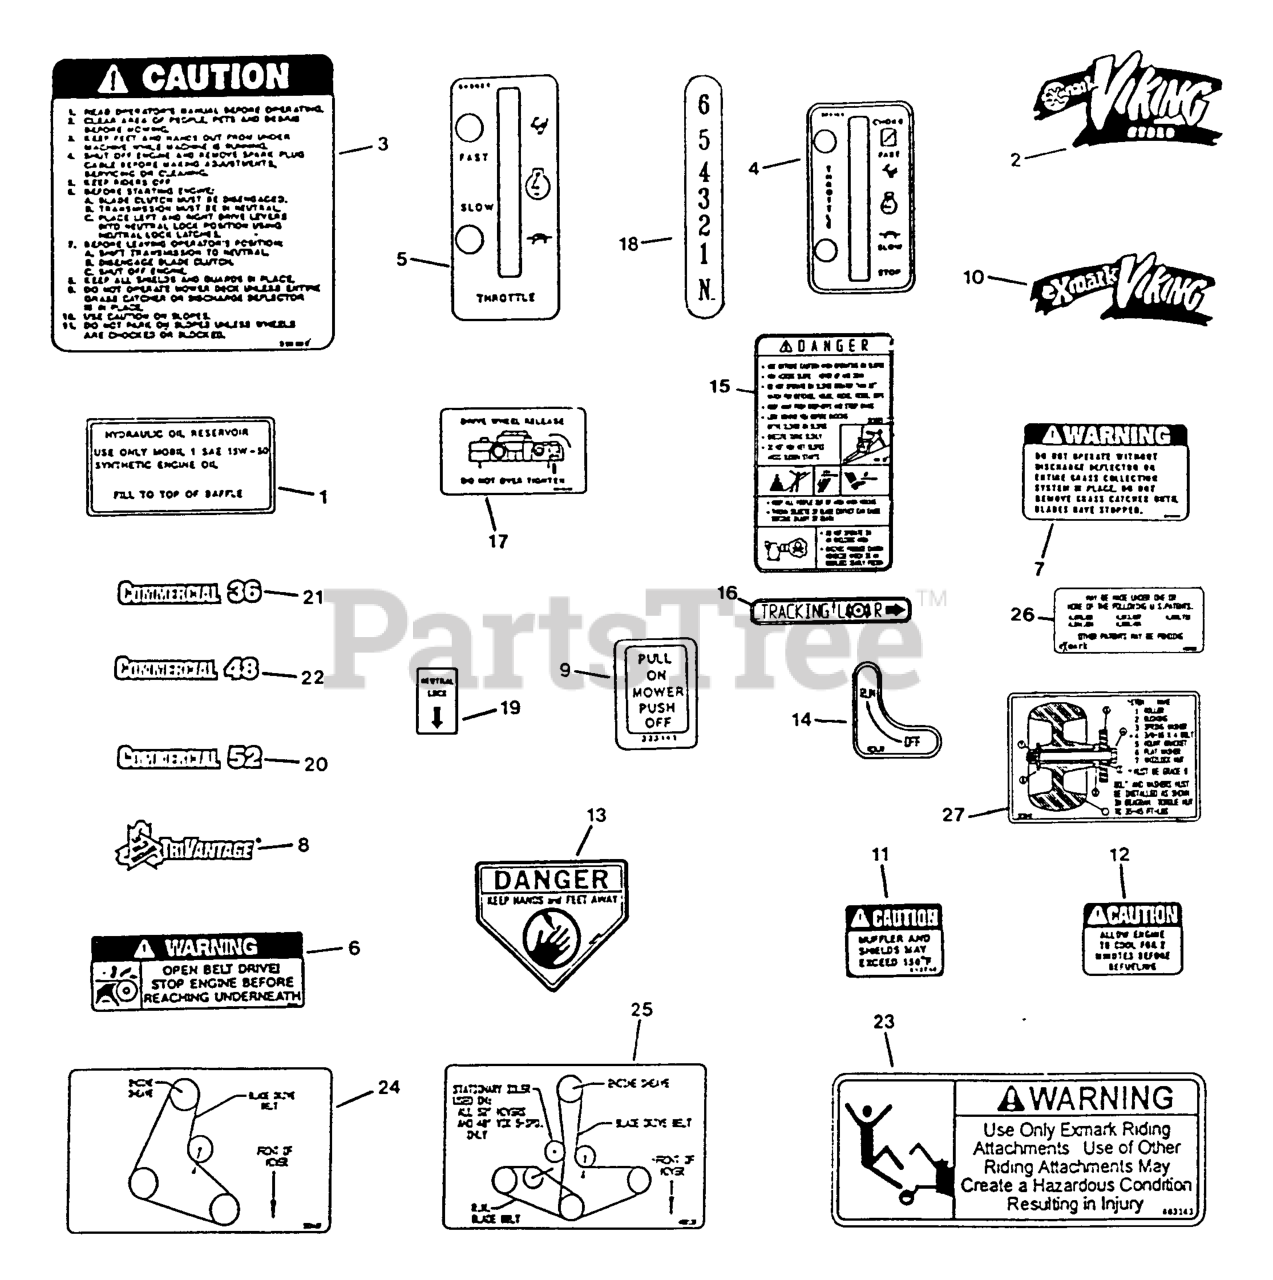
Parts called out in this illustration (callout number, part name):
1	DECAL,HYD TANK
3	DECAL,INSTRUCTIONAL
6	DECAL,BELT DRIVE
7	DECAL-WARNING, DISCHARGE
13	DECAL-DANGER
16	DECAL,TRACKING ADJUST
17	DECAL,DRIVE RELEASE
18	DECAL - SHIFTER
19	DECAL,NEUTRAL LOCK
20	DECAL,COMMERCIAL 52
21	DECAL,COMMERCIAL 36
22	DECAL,COMMERCIAL 48
23	DECAL,SULKY WARNING
24	DECAL,BELT ROUTING 32/36
27	DECAL,ROLLER MOUNTING
